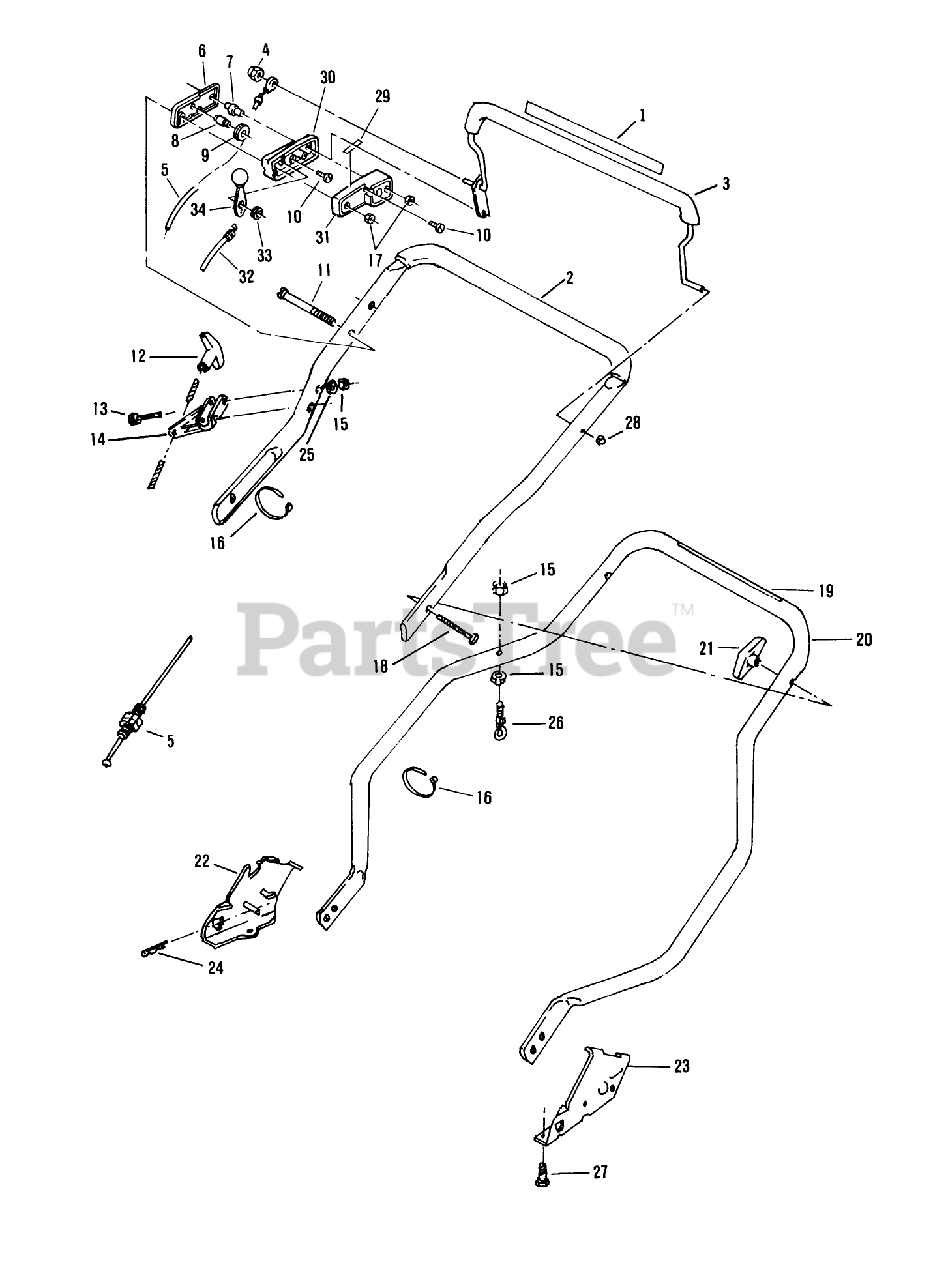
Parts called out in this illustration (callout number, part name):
4	NUT ACORN
5	CONTROL CABLE WES
7	COLUMN
8	PIN SKF
9	PULLEY PL
10	SCREW
11	SCREW
12	HANDLE START UM&D
15	LOCKNUT E
17	NUT C/LOCK E
18	BOLT QUALITY
21	NUT-WING
24	HAIR PIN
25	WASHER
26	EYE BOLT WAS MFG
27	SCREW
32	CABLE THROT WES
33	WASHER-SPRING
34	LEVER&KNOB AY WES
